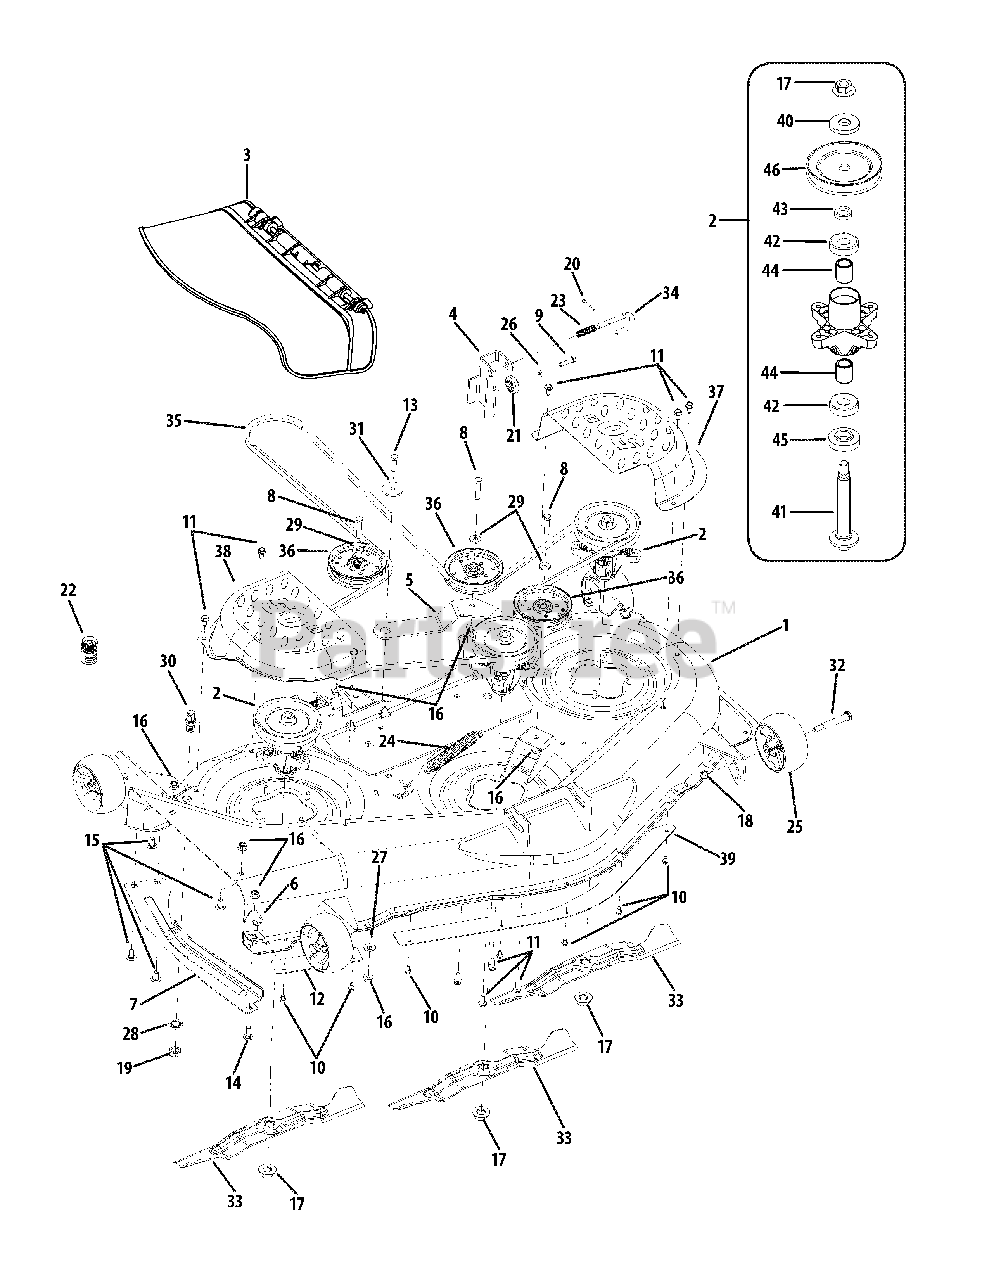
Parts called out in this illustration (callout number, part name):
1	Deck Housing
2	Spindle Assembly
3	Discharge Chute Assembly
4	Deck Hanger Bracket
5	Idler Arm
6	Stop Bracket
7	Finger Guard
8	Hex Cap Screw, 3/8-16 x 1.75
9	Hex Cap Screw, 5/16-18 x 1.25
10	Hex Washer Head Screw, 1/4-20 x .5
11	Hex Washer Head Screw, 5/16-18 x .750
12	Skirt, RH
13	Hex Cap Screw, 3/8-16 x 1.25
14	Hex Screw, 3/8-16 x 1.00
15	Carriage Screw, 3/8-16 x .75
16	Hex Insert Flange Lock Nut, 3/8-16
17	Hex Flange Nut, 5/8-18
18	Hex Flange Lock Nut, 3/8-16
19	Hex Nut, M16-1.5
20	Cotter Pin, 1/8 x 1.25
21	Deck Adjustment Gear
22	Water Nozzle Adapter
23	Compression Spring, .535 x 1.75
24	Extension Spring, .94 x 6.74
25	Deck Ball Wheel, 5.0
26	Lock Washer, 5/16
27	Bell Washer, .45 x 1.0 x .062
28	Internal Tooth Lock Washer, 5/8
29	Flat Washer, .38 x .93 x .110
30	Deck Wash Nozzle
31	Shoulder Spacer, .884 x .190
32	Shoulder Screw, .5 x 2.5 x 3/8-16
33	Blade, 2 in 1, 17.9
34	Deck Hanger Rod
36	Idler Pulley, 4.25 Dia
37	Belt Cover, LH
38	Belt Cover, RH
39	Center Skirt
40	Flat Washer, .76 x 1.50 x .12
41	Spindle Shaft, 5.75
42	Ball Bearing
43	Spacer, .79 x 1.25 x .175
44	Spacer, .80 x 1.10 x 1.32
45	Spacer, .79 x 1.82 x .55
46	V-Type Pulley, 5.39
